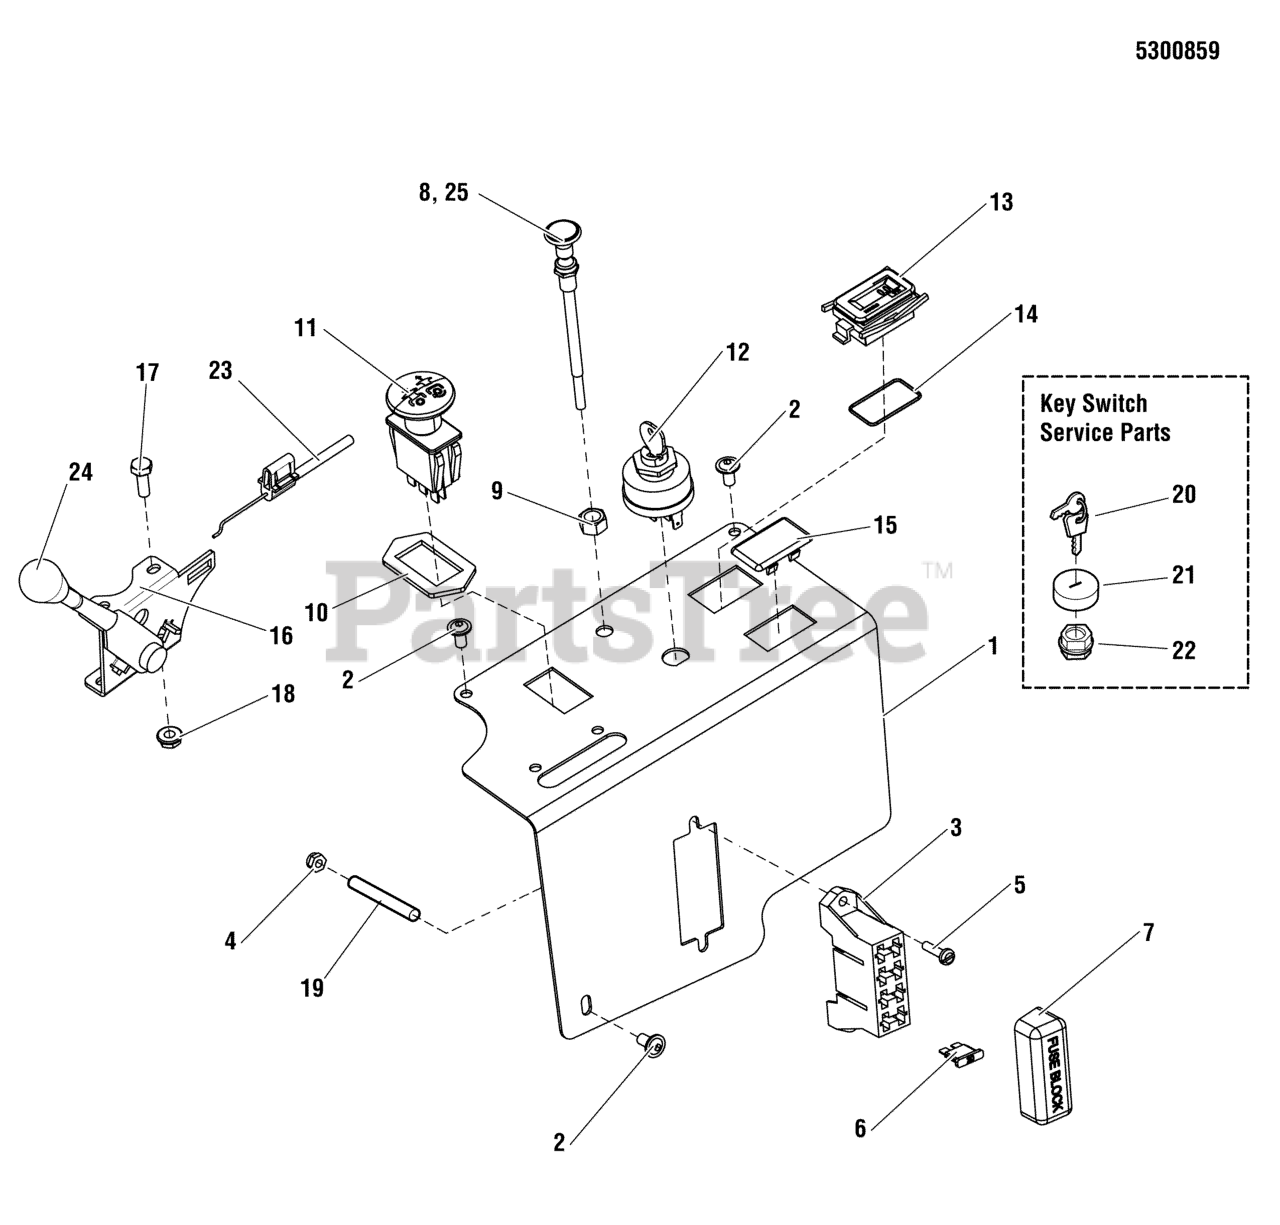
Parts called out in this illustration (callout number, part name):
1	PLATE, CONTROL PANEL, SNP - BLK
2	SCREW, ALLEN HEAD 1/4-20X.500 ZINC PHOS
3	FUSE BLOCK (SV)
4	NUT, #10-24 HEX NYLON LOCK
5	SCREW, #10-24 X 2" ROUND PHILLIPS
6	FUSE, ATP, 20 AMP (SV)
7	COVER, VINYL FUSEBLOCK
8	CABLE, CHOKE CONTROL, 47"
9	NUT, 3/8-24 HEX
10	RING, SWITCH RETAINER
11	SWITCH, BLADE ENGAGEMENT
12	SWITCH, IGNITION, 6 POST
13	HOUR METER
14	O-RING, 7/8 ID X 1/16 W
15	PLUG, .820X1.44 HOLE, BLACK PLASTIC
16	LEVER, THROTTLE CONTROL, HEAVY-DUTY
17	SCREW, #10-24 X 3/4" ROUND PHILLIPS
18	NUT, #10-24 HEX NYLON LOCK
19	SPACER, .20 X .38 X 1.25
20	KEY, IGNITION MOLDED SET
21	COVER, PLASTIC, SNAP ON
22	PLASTIC NUT
23	CABLE, THROTTLE, 42"
24	THROTTLE CONTROL HANDLE/KNOB
25	CABLE, CHOKE CONTROL, 56", DETENTED
